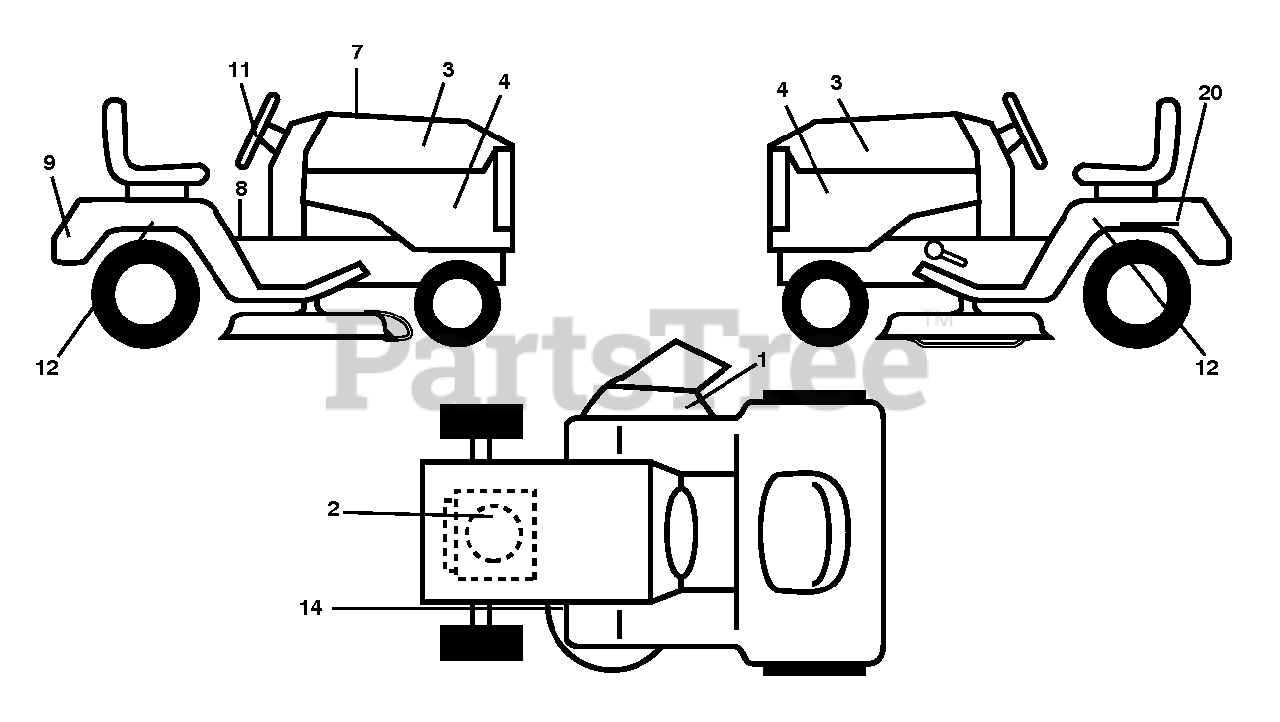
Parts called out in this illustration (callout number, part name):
1	DECAL.WARN.KEEP.HAND.AWAY
2	DECAL.ENGINE.B&S.(278443)
3	DECAL.HOOD.POULAN.PRO.SET
4	Poulan TBD
8	Fender Warning Decal, English
9	DECAL.REAR.FNDR.LOGO.POULAN.PR
11	DECAL.STEER.WHEEL.POULAN.PRO
14	DECAL V BELT SCHEMATIC
20	DECAL BTRY SYMBOLS
